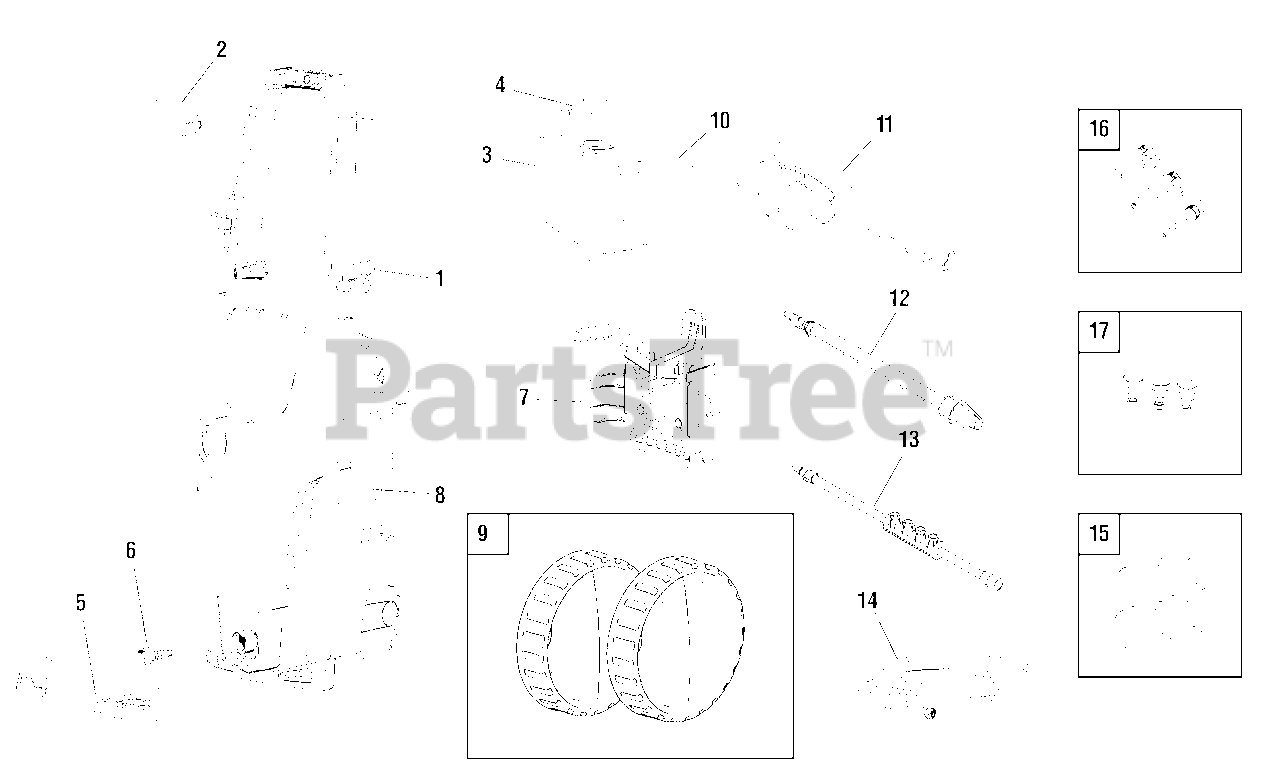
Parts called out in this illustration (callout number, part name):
3	CAP, Chemical Tank
5	FOOT, Stability
16	KIT, Compressor Nozzles
